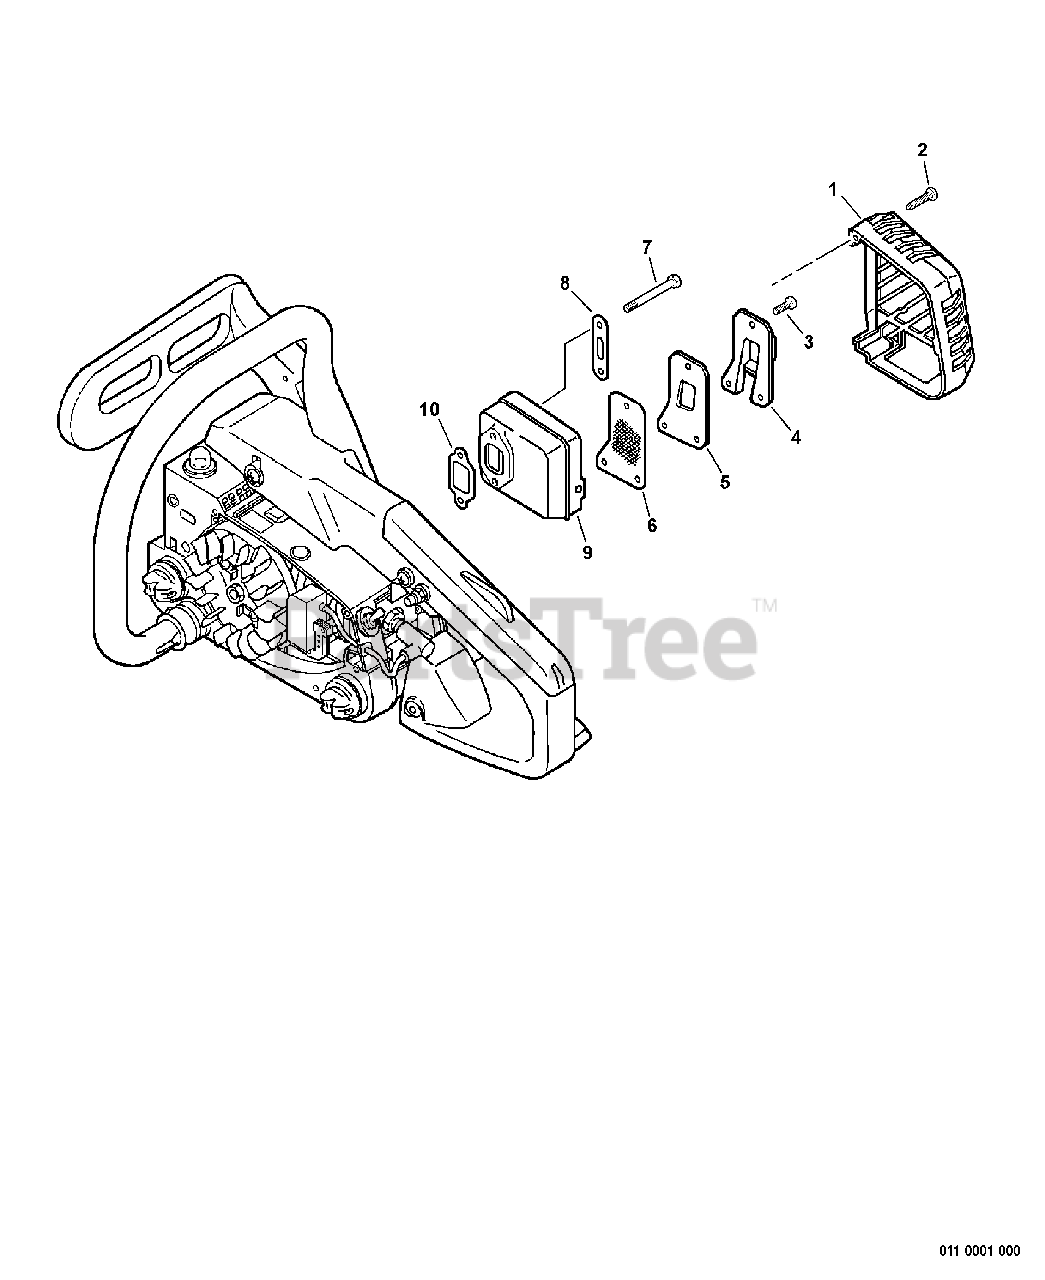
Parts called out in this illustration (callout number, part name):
1	COVER, MUFFLER
2	SCREW, TAPPING 5×20
3	SCREW 4×12
4	COVER, MUFFLER
5	GASKET, EXHAUST
6	SCREEN, SPARK ARRESTER
7	BOLT, FLANGE HSH 5×45
8	PLATE, EYE
9	MUFFLER
10	GASKET, MUFFLER
